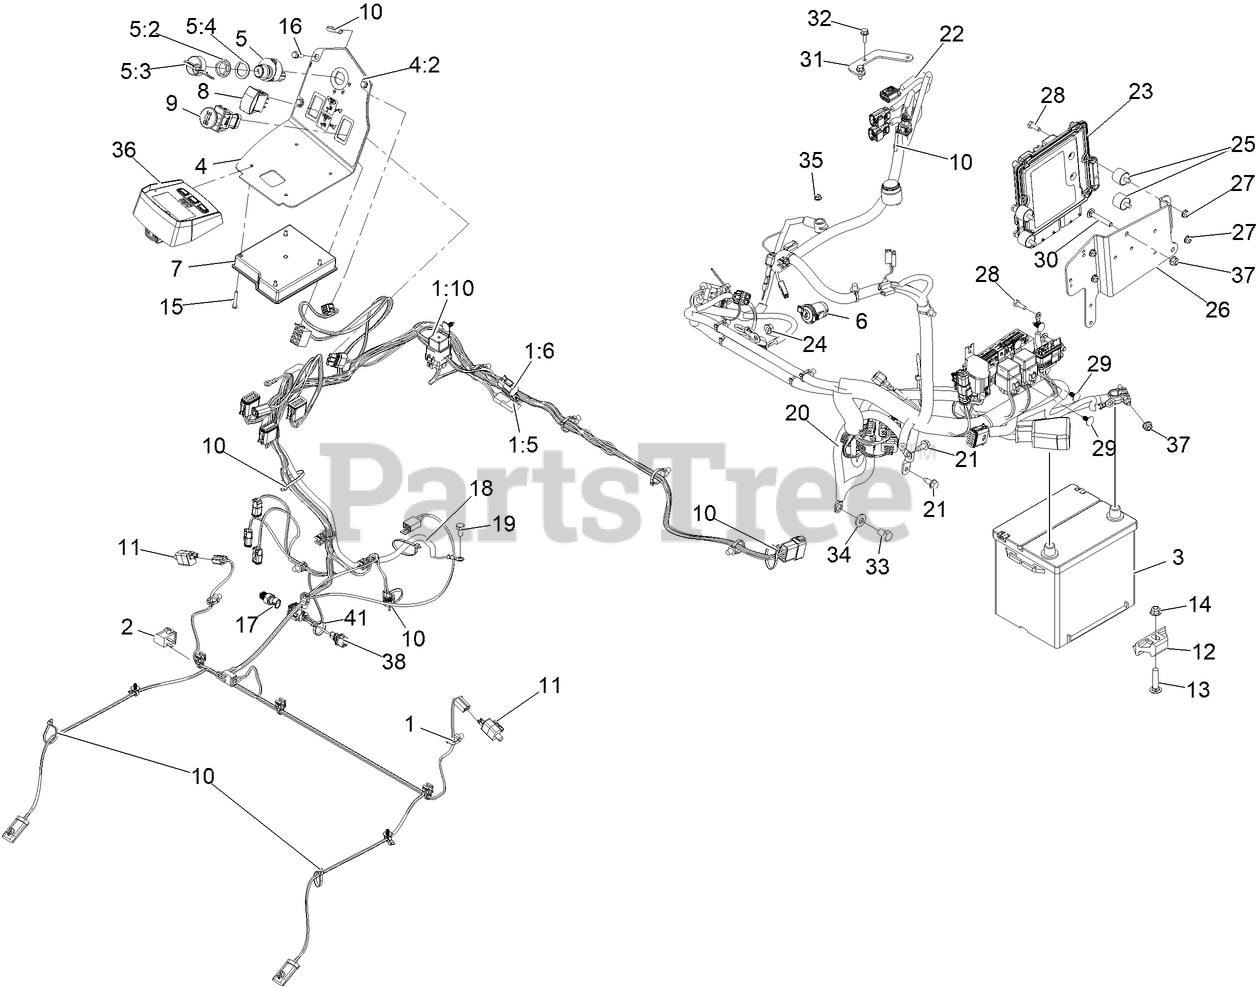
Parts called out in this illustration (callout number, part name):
1	HARNESS-WIRE, MAIN
1:5	Cap-Plug
1:6	CAP-PLUG, 6 WAY
1:10	RELAY-MINI
2	SWITCH-BAIL
3	Battery-Dry
4	CONSOLE ASM
4:2	DECAL-CONSOLE
5	IGNITION SWITCH ASM
5:2	NUT-MOUNTING
5:3	IGNITION KEY SET
5:4	WASHER-BACKUP
6	PORT-POWER, 12V
7	Module-Mcu
9	SWITCH-PTO, SEALED
10	TIE-CABLE
12	RETAINER-BATTERY
13	SCREW-CARR
14	NUT-HF, NI
15	SCREW-PPH
16	SCREW-HWH
17	Sensor-Temperature
18	HARNESS-WIRE, JUMPER
19	BOLT
20	CABLE-BATTERY
21	Screw-HWH 5/16-18 X 3/4 Tf
22	Harness-Wire, Yanmar
23	Electronic Control Unit
25	MOUNT-CYLINDRICAL
26	MOUNT-CONTROL UNIT, ENGIN
28	SCREW-HH
29	PLUG-PLASTIC
30	BOLT-CARR
31	BRACKET-WIRING, ENGINE
32	SCREW-HHF
33	SCREW-HH
34	WASHER-BELLEVILLE
36	MODULE, LDU
37	NUT-HF, NI
38	Harness-Jumper Temp Sense
41	TIE-CABLE
